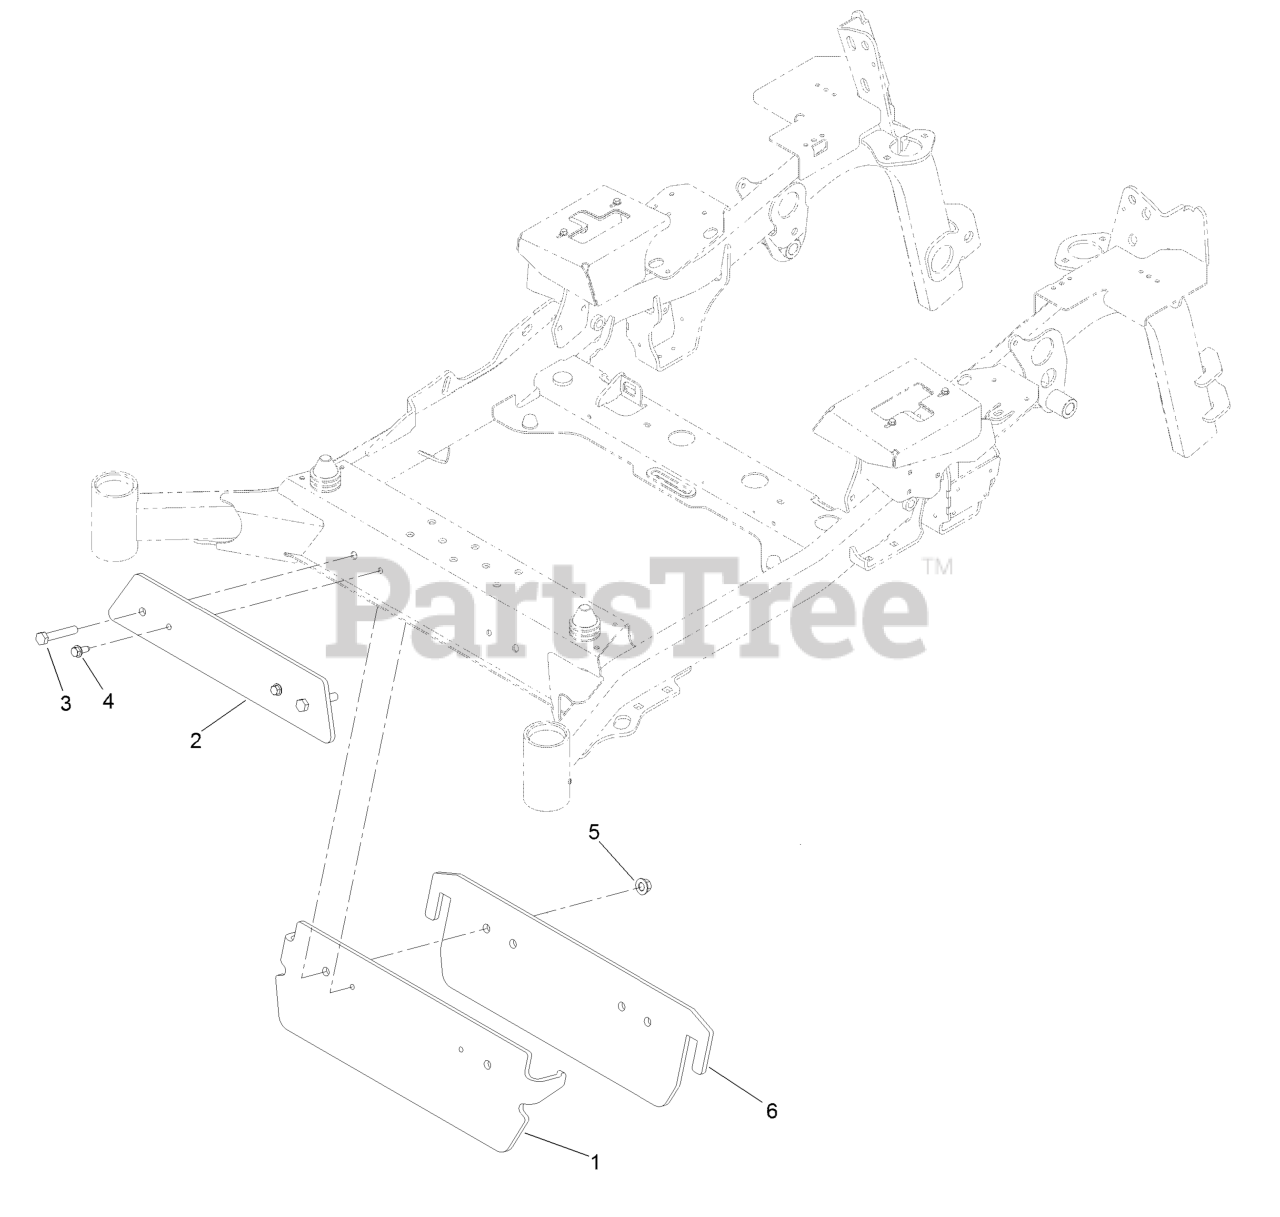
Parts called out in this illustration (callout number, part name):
1	Bracket-Weight
2	Weight-Outer
3	Screw-HH, TAP
4	Screw-Forming, Thread
5	Nut-Lock
6	Weight-Inner
